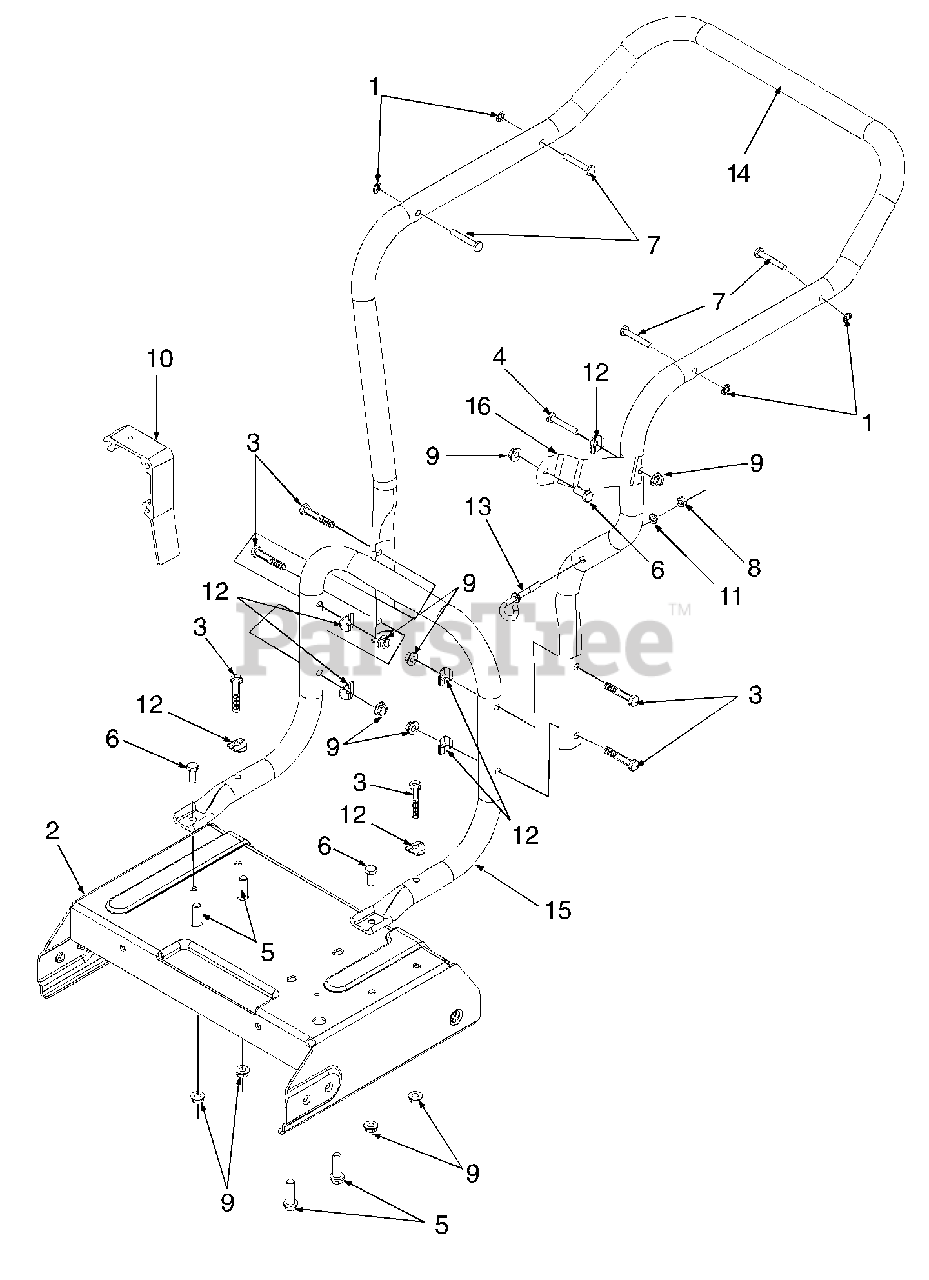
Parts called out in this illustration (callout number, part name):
1	Nut, Push
2	Frame Assembly
3	Screw, Hex Cap, 5/16-18 x 1.75
4	Screw, Hex Cap, 5/16-18 x 1.50
5	Screw, Hex Wash. Hd. Tapp, 3/8-16 x 1.25
6	Screw, Hex Cap, 5/16-18 x .75
7	Pin, Stud, .250 x 1.75
8	Nut, Hex, 1/4-28
9	Nut, Hex Flange Lock, 5/16-18
10	Adapter, Mounting
11	Washer, Lock, 1/4
12	Washer, Saddle, .32 ID x .93 OD
13	Bolt, Eye
14	Handle, Upper
15	Handle, Lower
16	Bracket, Chute Stabilizing
